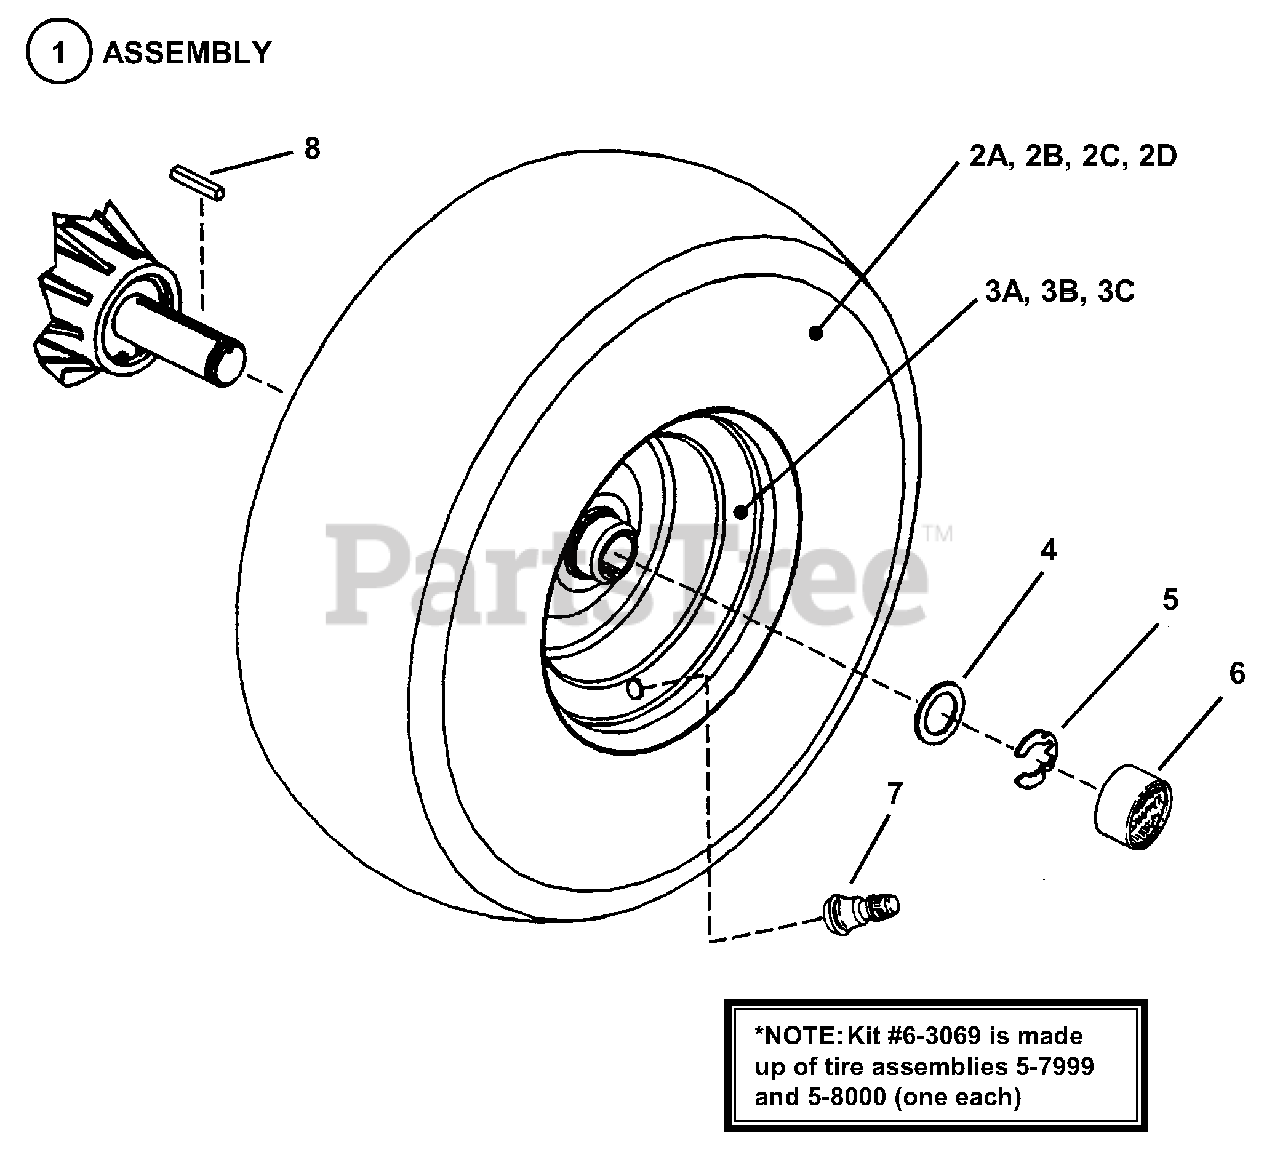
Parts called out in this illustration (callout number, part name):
1	ASSEMBLY, Rear Tire & Rim
1	ASSEMBLY, Right Hand Tire & Rim
2A	TIRE, 18 x 7.00-8 Multi-Trac Tread
2B	TIRE, 18 x 8.50-8 Multi-Trac Tread
2C	TIRE, 18 x 9.50-8
2D	TIRE, 18 x 8 All Terrain Tread
3A	RIM, 18 x 7.00
3B	RIM, 18 x 8.50
3C	RIM, 18 x 8
4	BUSHING, Machine
5	RING, Retaining, External 1"
6	CAP, Hub
7	STEM, Valve
8	KEY, M6 x 38 Square
